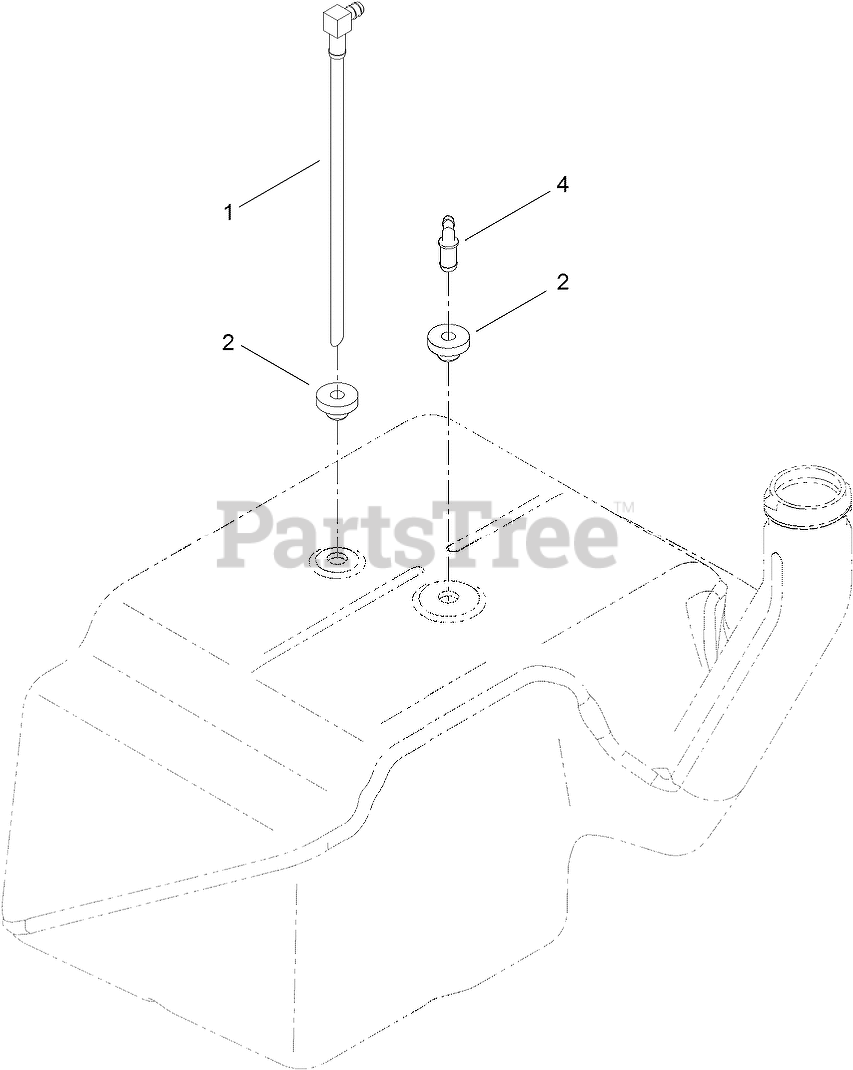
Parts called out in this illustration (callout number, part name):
1	TUBE-DROP
2	BUSHING
4	FITTING-PLASTIC
